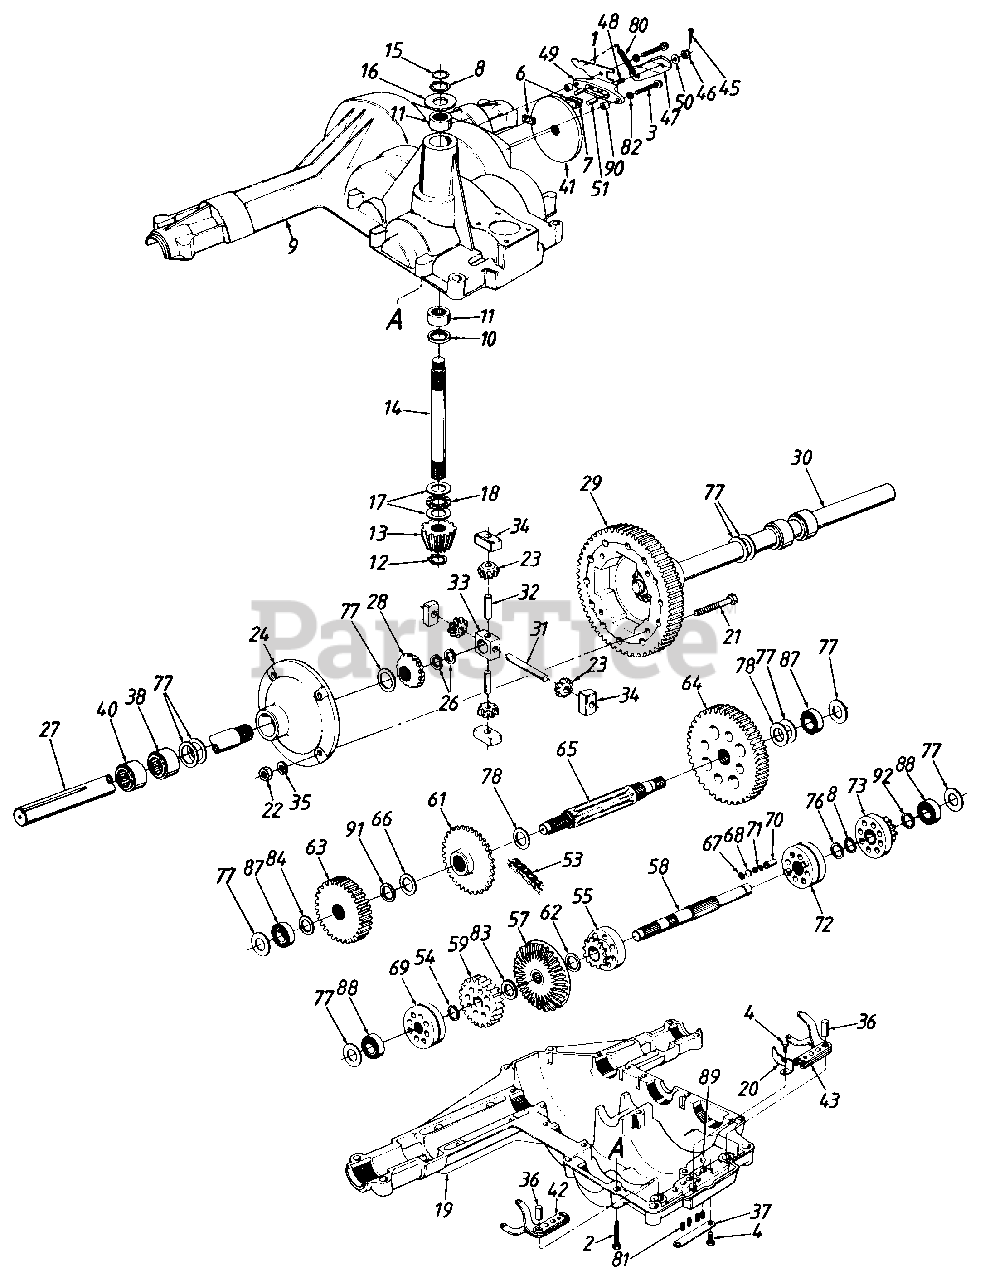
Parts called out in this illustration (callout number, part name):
1	Brake Return Bracket
2	Hex Bolt 1/4-20 x 1.25" Lg.
3	Hex Bolt 1/4-20 x 1.5 Lg. (Gr. 5)
4	Tap Scr. 1/4-20 x .38 Lg.
6	Brake Puck
7	Puck Plate
8	Retainer Ring
9	Upper Housing
11	Needle Brg. 5/8" l.D. x 7/8" O.D.
12	Snap Ring
13	Input Pinion 15T
16	Thrust Washer 5/8" l.D.
17	Thrust Washer
18	Thrust Bearing
19	Lower Housing
21	Hex Bolt 3/8-24 x 2.0 Lg.
22	Hex L-Nut 3/8-24 Thd. (Gr. 5)
23	Differential Gear 1OT
24	Differential Housing Cover Ass'y.
26	Retainer Ring
28	Differential Gear 14T
29	Differential Bull Gear 60T
32	Cross Shaft-Special
33	Differential Pinion Block
34	Differential Thrust Block
35	Spr. Wash. .39" l.D. x .62" O.D.
37	Spring Plate
38	Axle Bearing Ass'y.
40	Axle Bearing Ass'y.
41	Brake Disc
42	Shift Arm Ass'y.-R.H.
43	Shift Arm Ass'y.-L.H.
45	Cotter Pin 3/32" Dia.
46	Castle Nut 5/16-24 Thd.
47	Brake Actuating Arm
48	Sq. Hd. Bolt 5/16-24 Thd.
50	Fl-Wash. 11/32 I.D. x 7/8 O.D.
51	Brake Actuating Pin
53	#420 Chain 1/2 Pitch x 28 Links
54	Retainer Ring
55	Reverse Sprocket Ass'y.
57	Bevel Gear 47T
58	Drive Shaft
59	Spur Gear Ass'y.
61	Sprocket 22T
62	Fl-Wash. 81" l.D. x 1.18 O.D.
63	Spur Gear 31T
64	Spur Gear 45T
65	Output Shaft 9T
67	Internal Retainer Ring
68	Plug.44" Dia.
69	Forward Shift Collar
71	Drive Spring
72	Creeper Shin Collar
73	Creeper Collar Plate Ass'y.
76	Fl-Wash. 65" l.D. x 97" O.D.
77	Fl-Wash.
78	Fl-Wash. 1.0" l.D. x 1.56" O.D.
80	Ext. Spring 1.14" Lg.
81	Detent Spring
82	L-Wash. 1/4" l.D.
83	Fl-Wash. 5/8" l.D. x 1.0" O.D.
84	Fl-Wash. .68" x 1.12"
87	Ball Brg. .669" l.D.
88	Ball Bearing
89	Ball Detent .25" Dia.
90	Spacer .254" l.D. x .5" O.D.
91	Fl-Wash. .69 I.D. x 1.06 O.D.
92	Fl-Wash.
